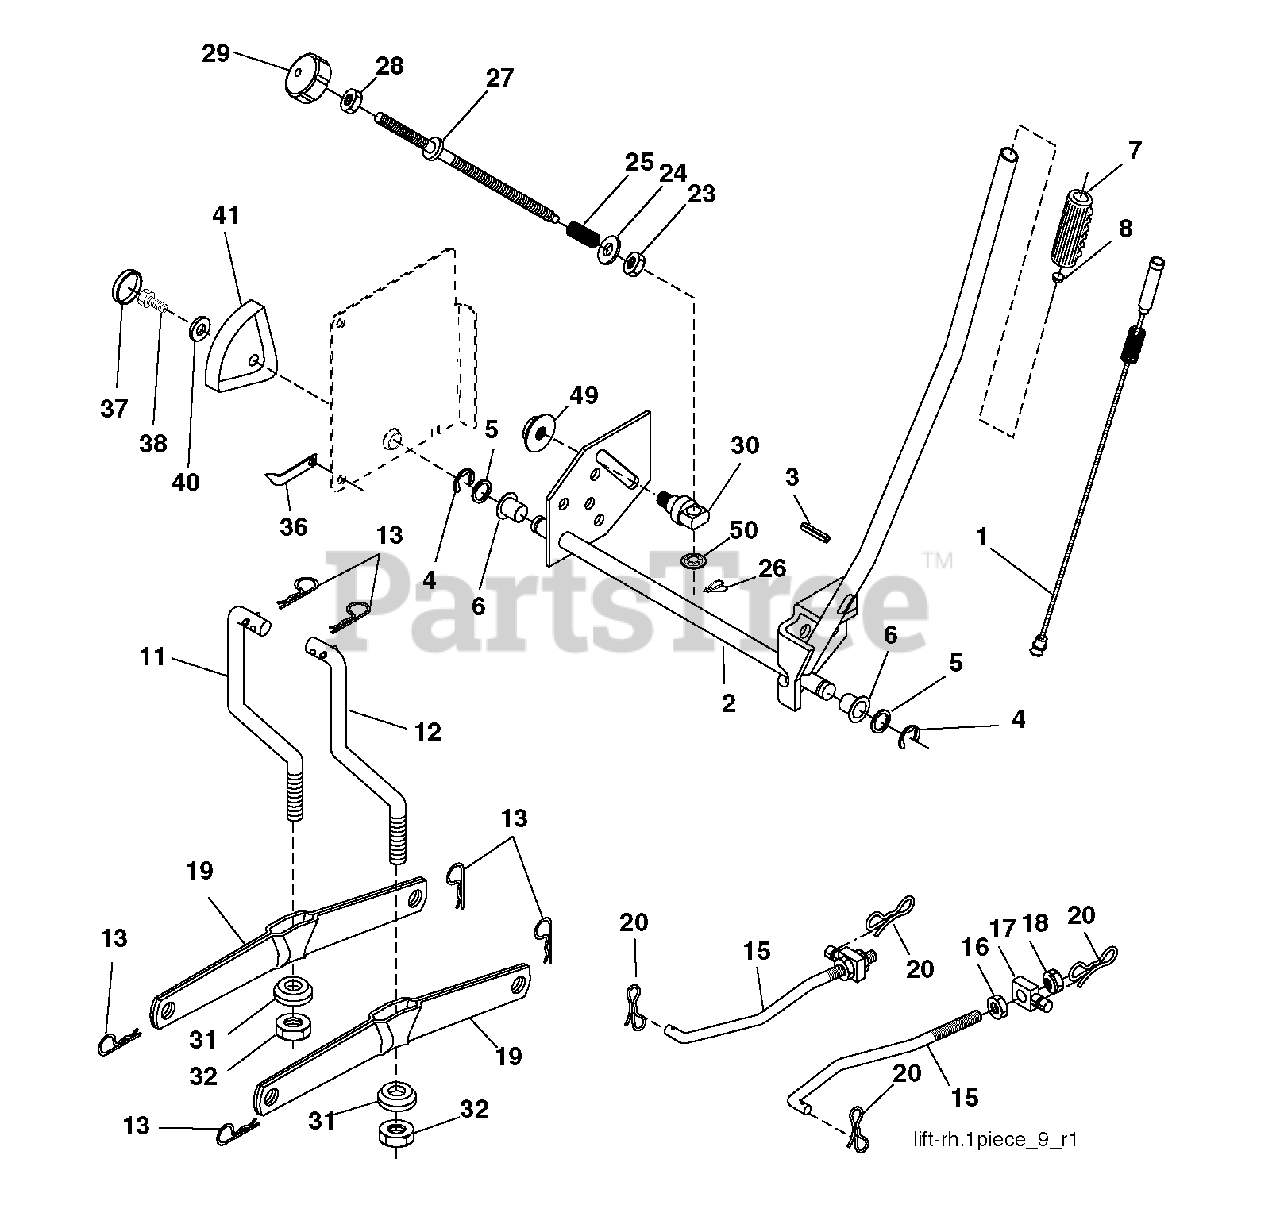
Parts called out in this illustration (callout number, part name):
1	PLUNGER.ASM.LIFT.LVR.BLK.17.32
2	SHAFT ASM R HANDLE
3	PIN GROOVE.
4	RETAINING RING LT
6	BEARING.NYLON
8	PLUNGER BUT KIT
11	LINK LIFT LH
12	LINK LIFT RH
13	Retainer Spring
15	LINK.SUSPENSION.FRONT
16	NUT.HEX.JAM.1/2-13
18	NUT.LK.W/WSH.1/2.
19	ARM.REAR.SUSPENSION
20	PIN.COTTER.7/16.BOW TI.
23	Special Nut
25	SPRING**
26	RETAINER CLIP
27	ROD ADJ LIFT
28	NUT
29	KNOB INF 3/8-16
31	BEARING.PIVOT.LIFT
32	NUT CROWNLOCK 3/8-24
36	POINTER, HEIGHT INDICATOR
38	SCREW 5/16-18X1
41	HEIGHT INDICATOR
49	NUT.HEX.FLANGE.3/8-16.LOCKNUT
50	NUT PUSH M
